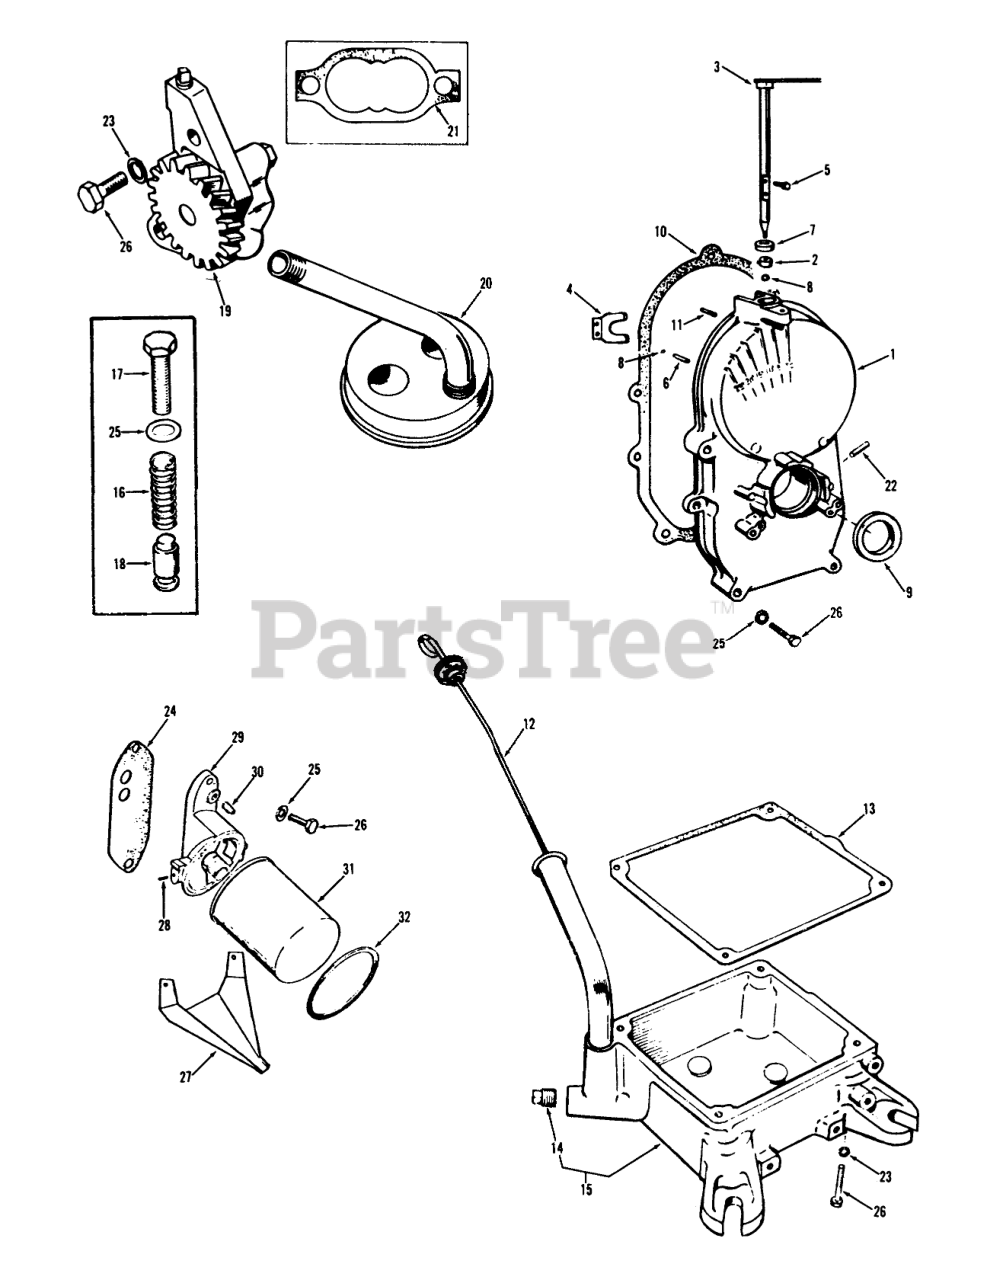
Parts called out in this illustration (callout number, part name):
1	Cover Assy
2	Governor Shaft Bearing
3	Shaft and Arm Assy-Governor
4	Yoke-Governor Shaft
5	Yoke Retaining Screw
6	Pin,Governor-Cup Stop
7	Oil Seal-Governor Shaft
8	Ball Bearing-Governor Shaft
9	Seal-Gear Cover
10	Gasket-Gear Cover Mounting
11	Pin, Gear Cover (5/16 x 1/8)
12	OIL FILL-CAP&INDICTR
13	Oil Base Mounting Gasket
14	Oil Drain Plug
15	Oil Base
16	Spring-Oil By-Pass Valve
17	Screw-Oil By-Pass 3/8-24 X 1
18	Oil By-Pass Valve
19	Oil Pump-Complete
20	Oil Pump Intake Assy
21	Oil Pump Gasket Kit
22	Fuel Pump Vacuum Tube
23	Oil Pump Mounting (1/4")
23	Oil Base Mounting (3/8")
24	Gasket-Oil Filter Pad Cover
25	Copper Washer 5/16 Gear Cover
25	Copper Washer-3/8 Oil Pressure
25	Copper Washer-3/8 Oil Filter
26	Hex Bolt-Oil Filter Adapter
26	Hex Bolt-Oil Pump 1/4-20 X 1
26	Hex Bolt-Gear Cover 2 1/4 Long
26	Hex Bolt-Gear Cover 1 3/4 Long
26	Hex Bolt-Oil Base To Block
27	Dain, Oil Filter
28	Hex HD Screw With Et Washer
29	Oil Filter Adapter
30	Square HD Plug
31	Oil Filter
32	Oil Filter Air Seal
